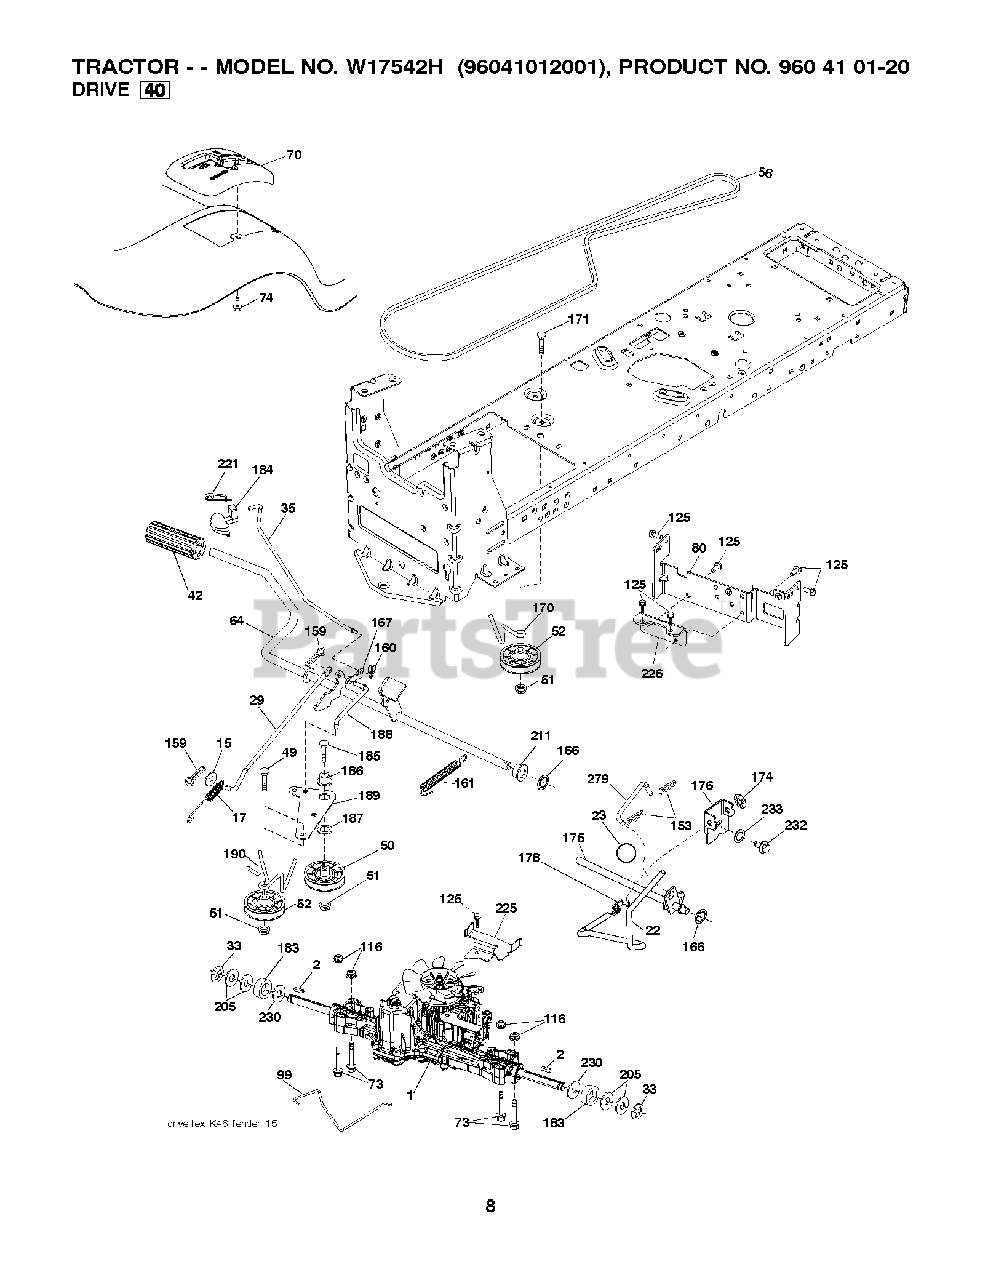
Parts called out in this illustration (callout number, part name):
1	Poulan TBD
2	SQUARE KEY
17	SPRING.BRAKE.K46.GREEN
22	ROD.SHIFT.FENDER.TLT.2006
29	ROD.BRAKE.K46
33	E-RING LT
35	ROD.BRAKE.PARKING.LT.T
49	BOLT
50	IDLER.FLAT.910.OFFSET
51	NUT LOCK FLG 3/8-16 UNC
52	IDLER.V-GROOVE.910.OFFSET
56	V-BELT.MOWER.92.40.42/K46
64	SHAFT.ASM.PEDAL.BRAKE.
70	CONSOLE.SHIFT.STL.HYD.BLACK
73	BOLT HEX 5/16-18 GR 5
74	SCREW.HI-LO.CONSOLE
80	STRAP TORQUE.ASM.K46/18"TEX
99	ROD.SPRING.BYPASS.K46.LT.Z
116	NUT LOCK HEX FLANGE 5/16-18
125	SCREW
159	COTTER PIN
160	RETAINER CLIP
161	SPRING, RETURN LT
166	NUT.PUSH.625.2006
167	LATCH.BRAKE.SPRING
170	KEEPER.V-IDLER.CENTER.
171	BOLT
174	NUT.PUSH.500.2006
175	SHAFT ASM SHIFT
176	ARM.CLEVIS.ROD.SHIFT
178	SPRING.SHIFT.GT2006
183	SPACER AXLE
186	SPACER.RETAINER
187	WASHER 12/32X2X10GA
188	LINK.CLUTCH.GROUND.DRIVE
189	BELLCRANK.GROUND.DRIVE.TEX.
190	KEEPER.BELLCRANK.DRIVE
211	BUSHING.SHAFT.BRAKE.HAND
221	RETAINER.SPRING.CLIP.H
225	KEEPER.BELT.TRANSAXLE.K46
226	BRACKET.MOUNT.TORQUE.K46.TLT
230	WASHER.HARDENED
232	BOLT FIN HEX 7/16-14 X 1
233	WASHER SERRATED
279	LINK.SHIFT.T/A.K46.FEND.TX
